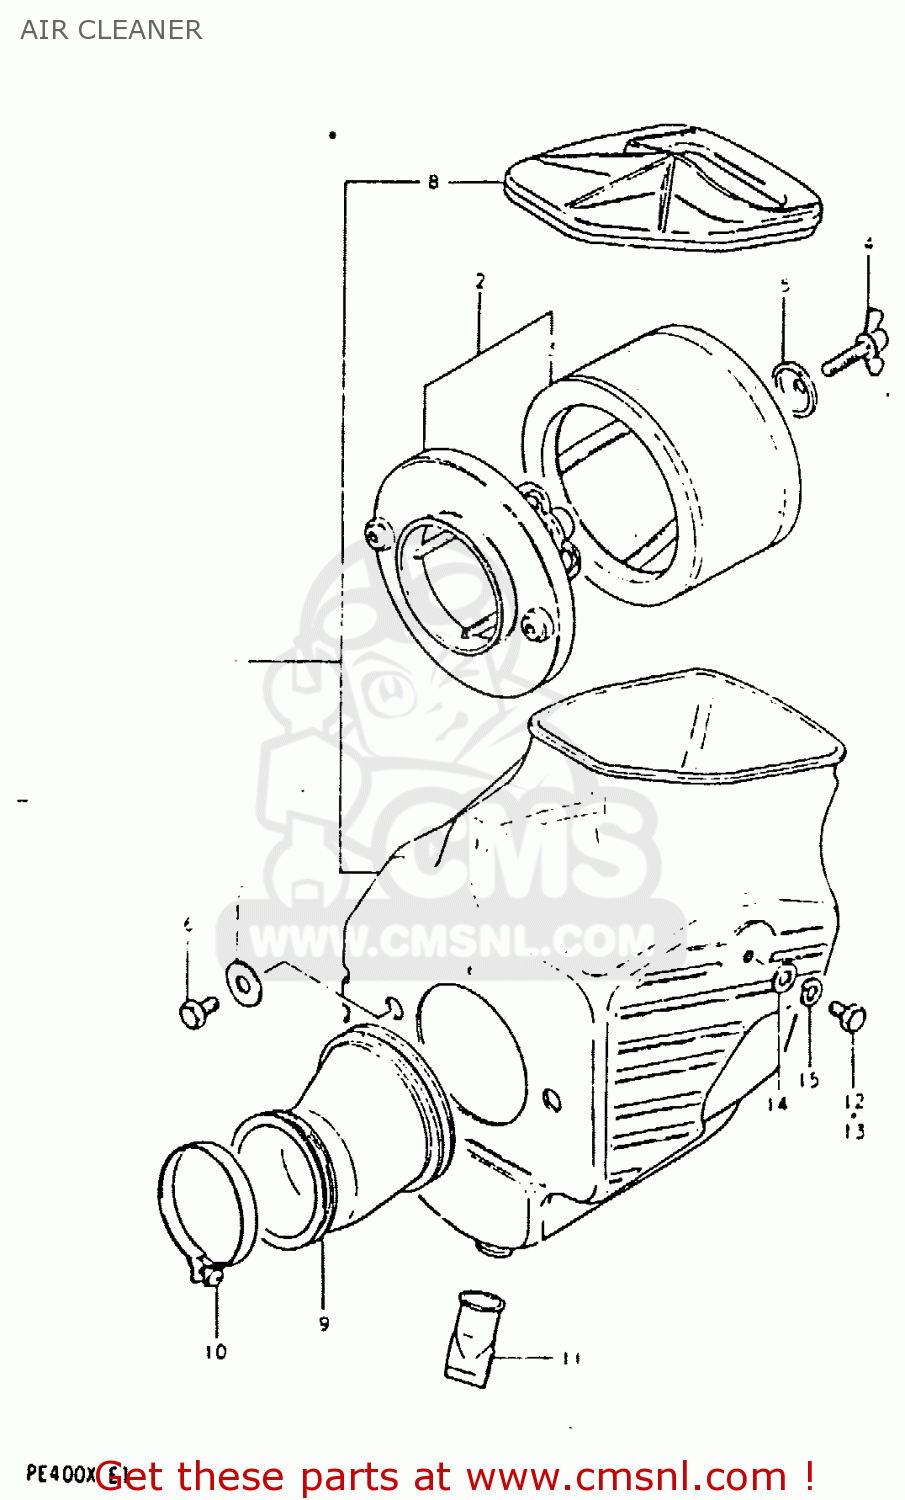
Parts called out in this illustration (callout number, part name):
1	CLEANER ASSEMBLY,AIR
2	FILTER ASSY
3	FILTER
4	WING BOLT,AIR CLEANER
5	HOLDER,FILTER
6	BOLT
7	SPACER,AIR CLEANER,REAR
8	CAP,AIR CLEANER
9	TUBE,AIR CLEANER OUTLET
10	CLAMP
11	HOSE, DRAIN
12	BOLT
13	SCREW
14	WASHER
15	LOCK WASHER
